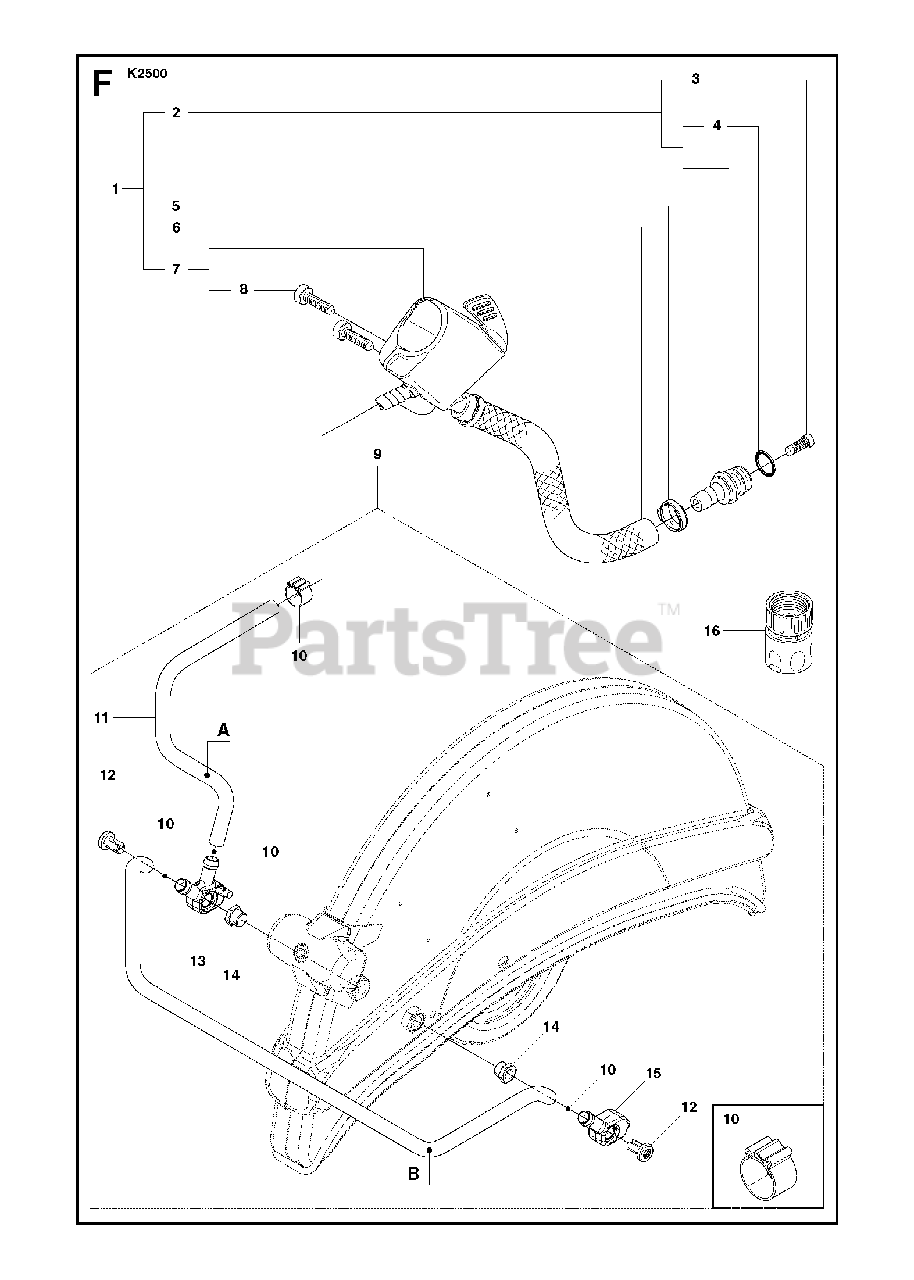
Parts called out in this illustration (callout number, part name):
1	HOSE KITIncl. 2, 5-7
2	NIPPLEIncl. 3, 4
5	HOSE CLAMP
7	VALVE ASSYIncl. 8
9	HOSE KIT15-okt
11	HOSE
12	SCREW ITXSCM
